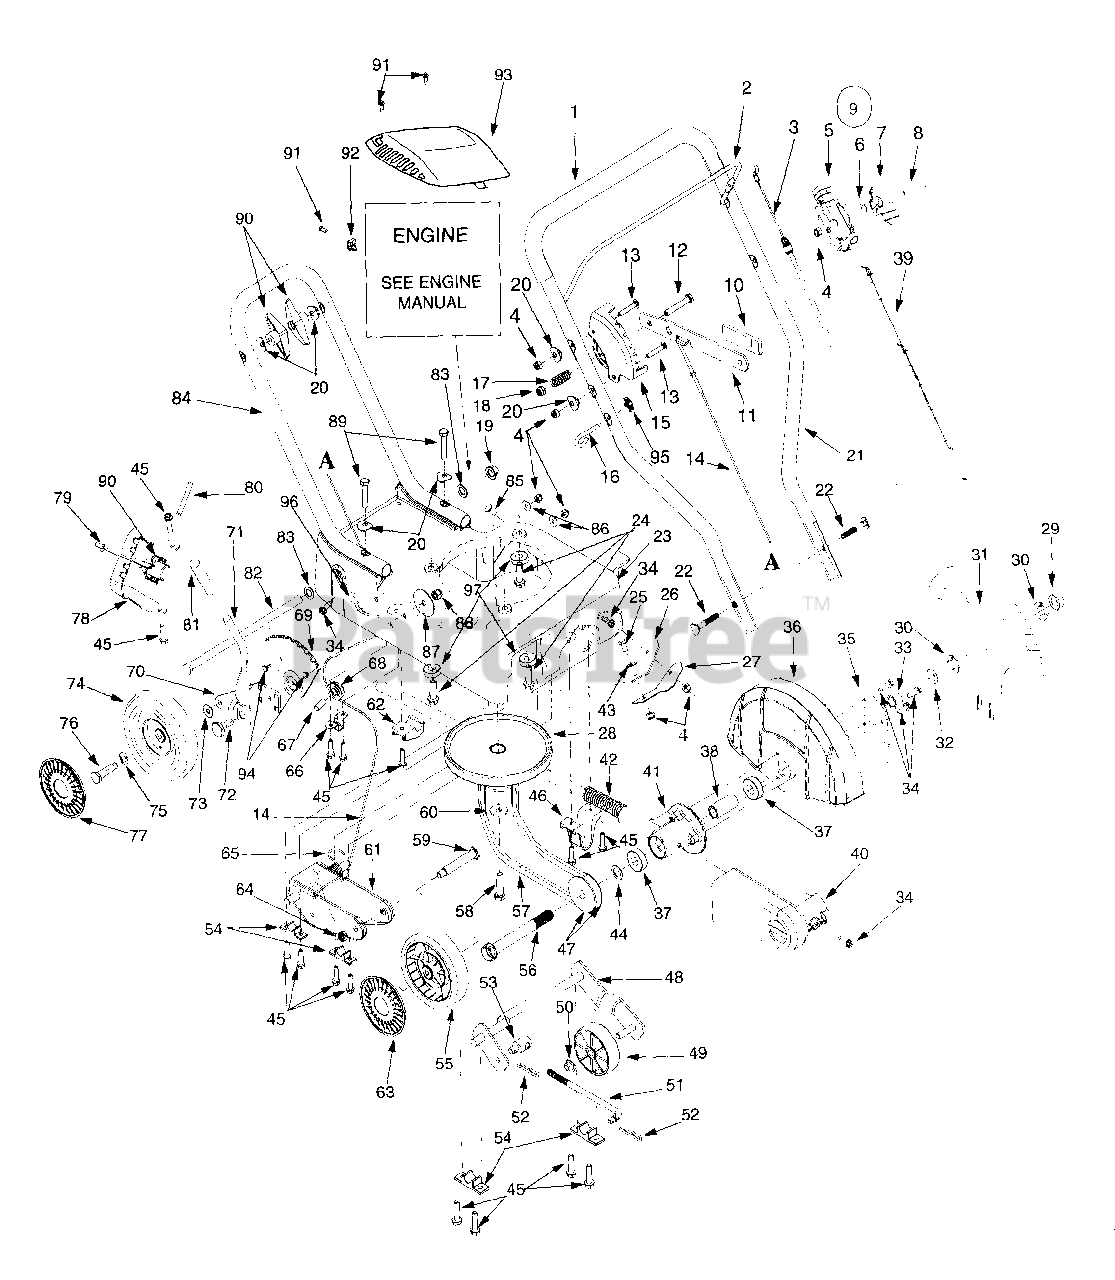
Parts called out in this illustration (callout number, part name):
1	Foam Grip
3	Control Cable
4	Hex Lock Nut 1/4-20 Thd.
5	Throttle Hsg.
6	Curved Washer .663 x .980 x .014
7	Throttle Lever
8	Screw Oval C-Sunk 1/4-20 x 1.81 Lg.
9	Throttle Comp.
10	Grip - Black
12	Hex Screw 5/16-18 x 2.0 Lg.
13	Carriage Bolt 1/4-20 x 1.50 Lg.
14	Depth Cable
15	Depth Bracket
16	Eye Bolt 1/4-20
17	Compression Spring .550 O.D. x 1.3
18	Hex Lock Nut 5/16-18
19	Push Cap x 1/2 Rod
20	Washer .320 ID x .93 O.D.
23	Edger Base Ass'y
24	Tapp Screw w/Hex Lock Wash 3/8-16
25	Hex Screw 1/4-20 x .50 Lg.
26	Discharge Shield Deflector
27	Deflector Keeper
28	Engine Pulley
29	Hex Jam Nut 5/8-18
30	Bell Washer .63 I.D. x 1.25 O.D. x .18
32	Hex Jam Nut 5/8-18
33	Spacer .628 x .875 x .545 Lg.
34	Hx Scr. w/Wash.: TT: 1/4-20 x .750 Lg.
37	Ball Bearing .62 I.D. x 1.38 O.D. x .4
38	Spacer .628 x .875 x 1.818 Lg.
39	Throttle Cable
40	Belt Guard
41	Spindle w/Insert
42	Compression Spring: Arbor
43	Flat Washer .283 I.D. x .75 O.D. x .030
44	Flat Washer .635 I.D. x .93 O.D. x .06
45	Hex Screw w/Wash 1/4
46	Front Rod Handler
47	Pulley
50	Push Cap x 3/8 Rod
51	Rod 5/16-24
52	Cotter Pin .072 x 1.12
53	Ferrule 5/16-24 x .312
54	Slack Bushing .515 Dia x .62
55	Wheel 7" x 2" Link w/BB
56	Hex Bolt 5/8-18 x 5.25 Lg.
57	V-Belt
58	Hex Screw: 3/8-24 x 1.50 Lg.
59	Shoulder Screw .500 x 2.62: 3/8-16
60	Bell Wash. .396 I.D. x 1.140 O.D. x .095
61	Front Wheel Brkt Ass'y.
62	Rear Rod Handler
63	Hubcap: Spoke w/Hole Beige
64	Jam Lock Nut 3/8-16
65	Torsion Spring
68	Roller Cable
69	Index Plate
70	Pivot Arm
71	Spring Lever
72	Shoulder Bolt .500 x .434 Lg.
73	Bell Wash. .401 I.D. x .870 O.D. x .063
74	Wheel - 8" x 2" Link Beige w/BB
75	Wave Washer .510 I.D. x .750 D.D.
76	Shoulder Bolt .498 x 1.445: 3/8-16
77	Hubcap: Radial Spoke Beige
78	Tilt Bracket
79	Adj. Lever Ass'y
80	Pin 1/4 x 2.0" Lg.
81	Foam Grip
82	Curb Axle
83	Flat Wash. .531 I.D. x .875 O.D. x .06
86	Flat Wash. .285 I.D. x 1.25 O.D. x .06
87	Flat Wash. .406 I.D. x 1.92 O.D. x .06
88	Hex Lock Nut 3/8-16
89	Hex Screw 5/16-18 x 1.75 Lg.
90	Torsion Spring
90	Wing Knob Nut 5/16-18
91	Hex Scr. w/Wash.: 7: #10-32 x .625 Lg.
92	Clamp B&S Throttle
93	Engine Shroud
94	Screw Std. 1/4-20 x .75 Lg.
95	Handle Knob
